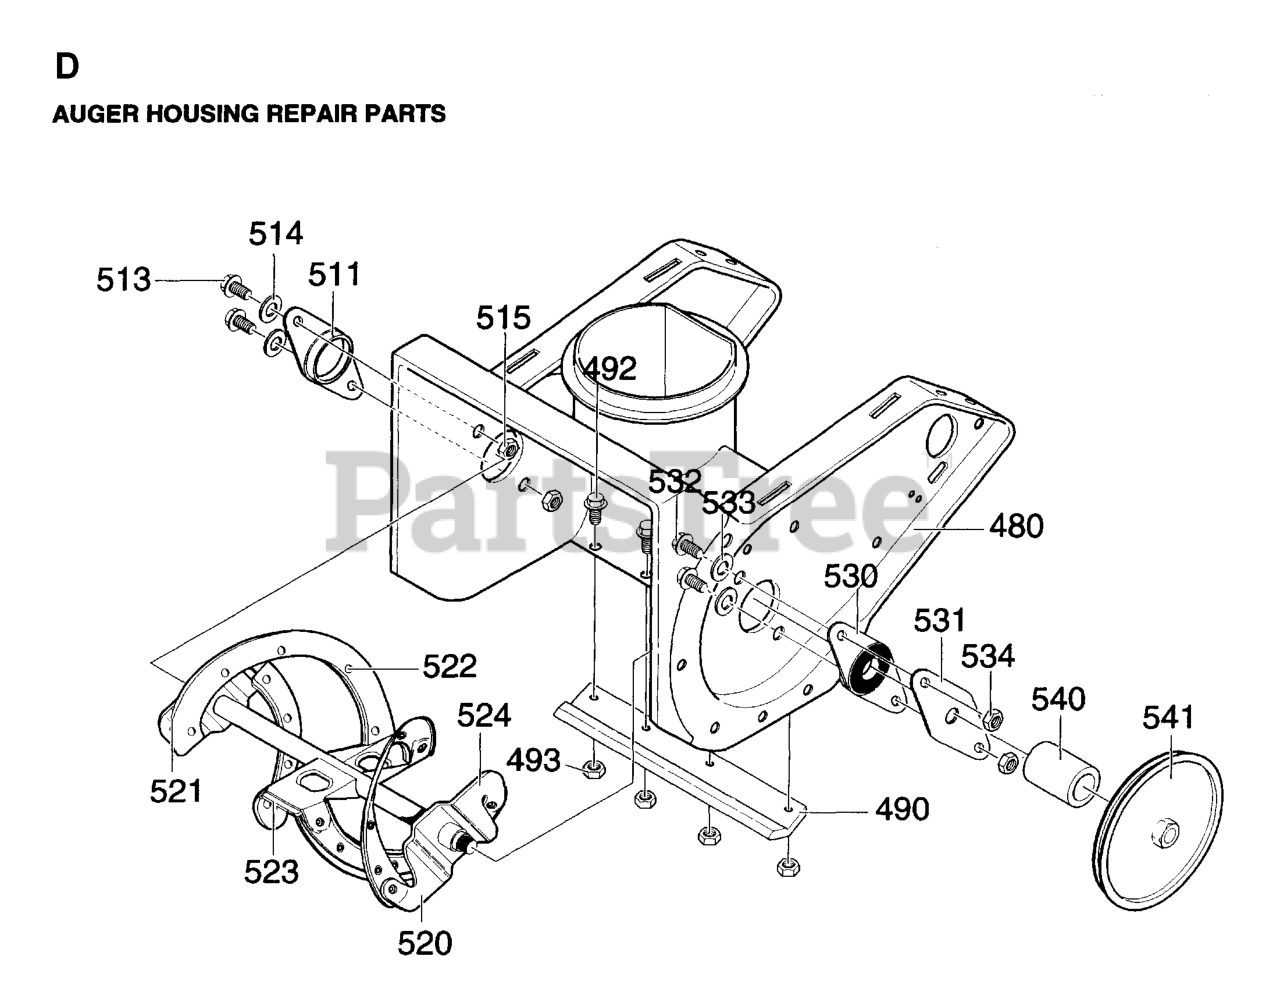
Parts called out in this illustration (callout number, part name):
490	SCRAPER
513	BOLT
534	NUT.CROWNLOCK.1/4
